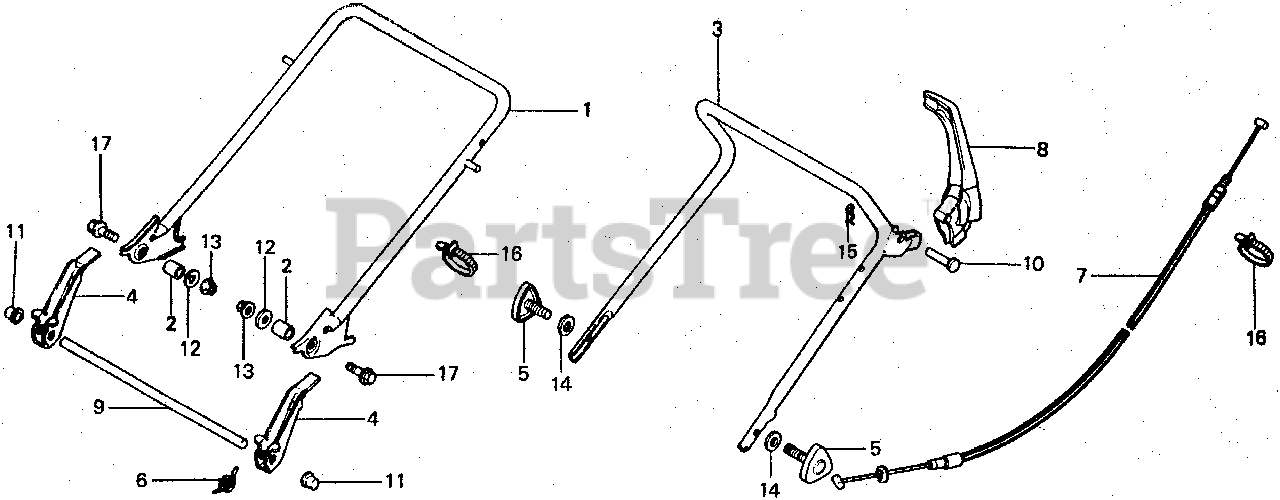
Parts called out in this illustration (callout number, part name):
1	HANDLEBAR (LOWER)
2	COLLAR (LOWER)
3	PIPE (UPPER) (NOT AVAILABLE)
4	LEVER, LOCK
5	GRIP, HANDLE JOINT
6	SPRING, HANDLE
7	CABLE, ROTO-STOP CLUTCH
8	LEVER, ROTO-STOP CLUTCH
9	SHAFT, SHIELD
10	PIN, CLUTCH LEVER
12	WASHER (8MM)
13	NUT, FLANGE (8MM)
14	WASHER, PLAIN (8MM)
15	PIN, LOCK (8MM)
16	BAND B1, CABLE
16	BAND B2, CABLE HARNESS
17	BOLT, FLANGE (8X32)
